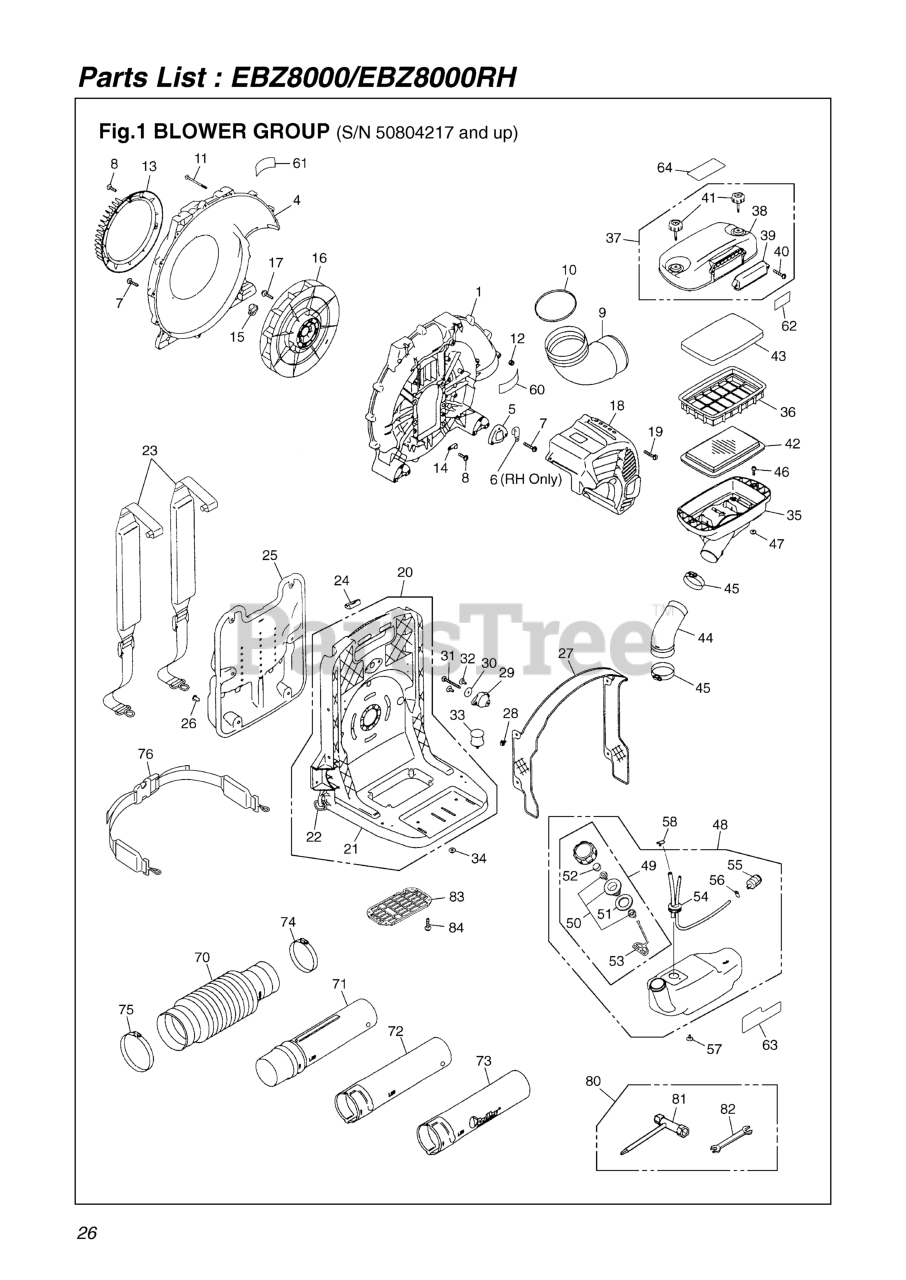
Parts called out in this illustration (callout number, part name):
1	VOLUTE CASE (REPLACES -55A3)
4	VOLUTE COVER
6	CLAMP
7	SCREW
9	ELBOW
10	O-RING
11	SCREW TORX
12	NUT (B)
13	COVER, INLET (REPLACES -55D3)
14	CLAMP (RPLS 1140-72231)
15	CAP
16	FAN (REPLACES 848-L58-5212)
17	BOLT
18	ENGINE COVER (RPLS -31A1)
19	SCREW
20	FRAME COMP. (RPLS. -3513)
21	FRAME
22	RING (REPLACES -21120)
23	BAND ASSY
24	CLIP
25	PAD
26	CLIP (RPLS 3490-21320)
27	NET COMP
28	CLIP
29	DAMPER, UPPER
30	WASHER
31	BOLT, TORX
32	SCREW TORX
33	DAMPER, LOWER
34	NUT, M6
35	BODY, CLEANER
36	CASE, INNER
37	COVER ASSY
38	COVER
39	COVER
40	SCREW
41	KNOB BOLT
42	ELEMENT (PAPER)
43	ELEMENT (FOAM) (RPLS -82320)
44	HOSE
45	CLAMP
46	BOLT (USE 848-815-2000)
47	NUT
48	TANK-A
49	CAP ASSY (RPLS -85201)
50	HOLDER (REPLACES -85230)
51	PACKING
52	FILTER
53	STOPPER
54	PIPE COMP
55	FILTER ASSY
56	CLIP (REPLACES 2841-31280)
57	SCREW TORX
58	CLIP
60	LABEL, CAUTION (RPLS -31910)
61	LABEL, NET
62	LABEL,EBZ8000
64	LABEL
70	FLEX HOSE
71	SWIVEL JOINT
72	PIPE, STRAIGHT
73	PIPE, END
74	CLAMP
75	CLAMP
76	BAND ASSY
80	TOOL-SET
81	SPANNER, 8 X 10 (RPLS 2540- )
83	NET
